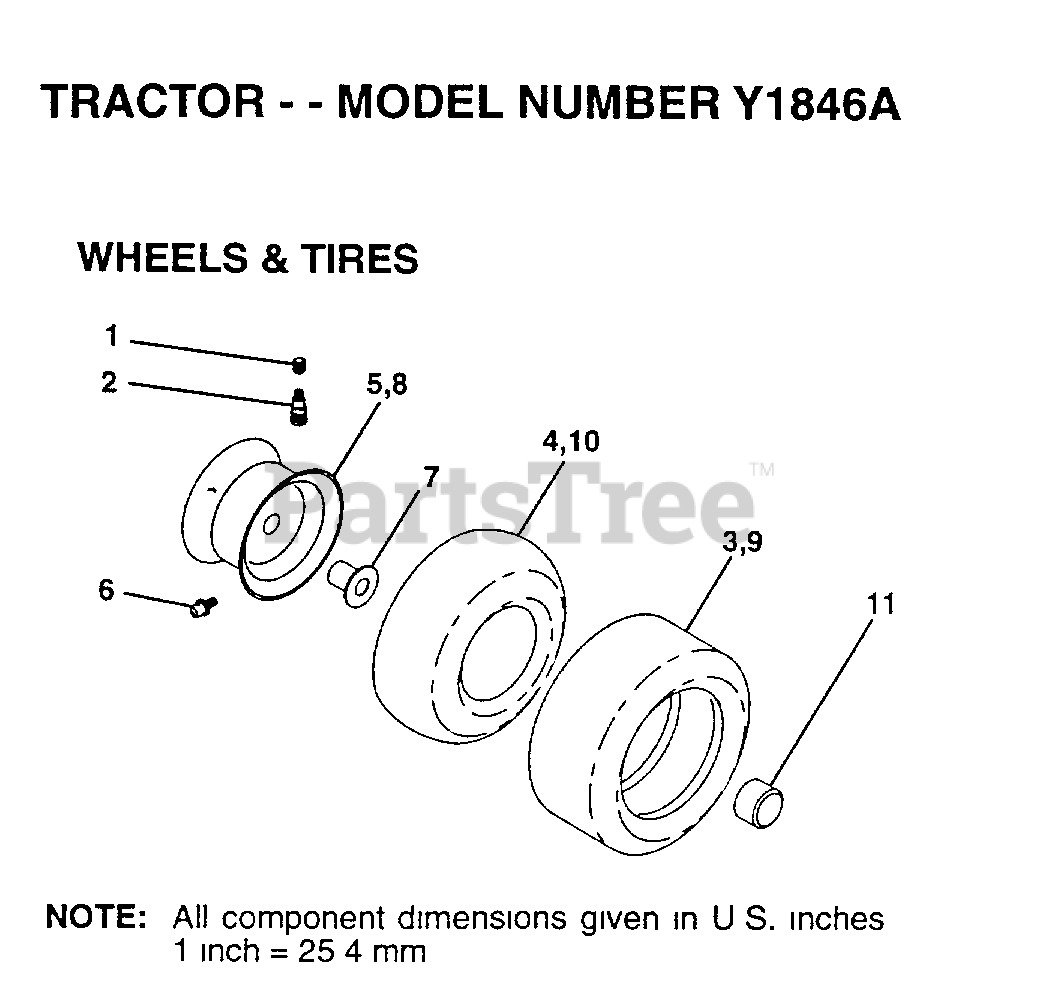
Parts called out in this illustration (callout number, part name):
1	VALVE CAP
2	VALVE STEM LT
4	TUBE.5.3/4.5/6
5	"RIM ASM 6"" FRT"
6	FITTING LT
7	"FLANGE, BEARING"
8	"RIM AS 8"" REAR"
9	TIRE.20X8-8
10	TUBE.18X9.5-8
11	HUB CAP
